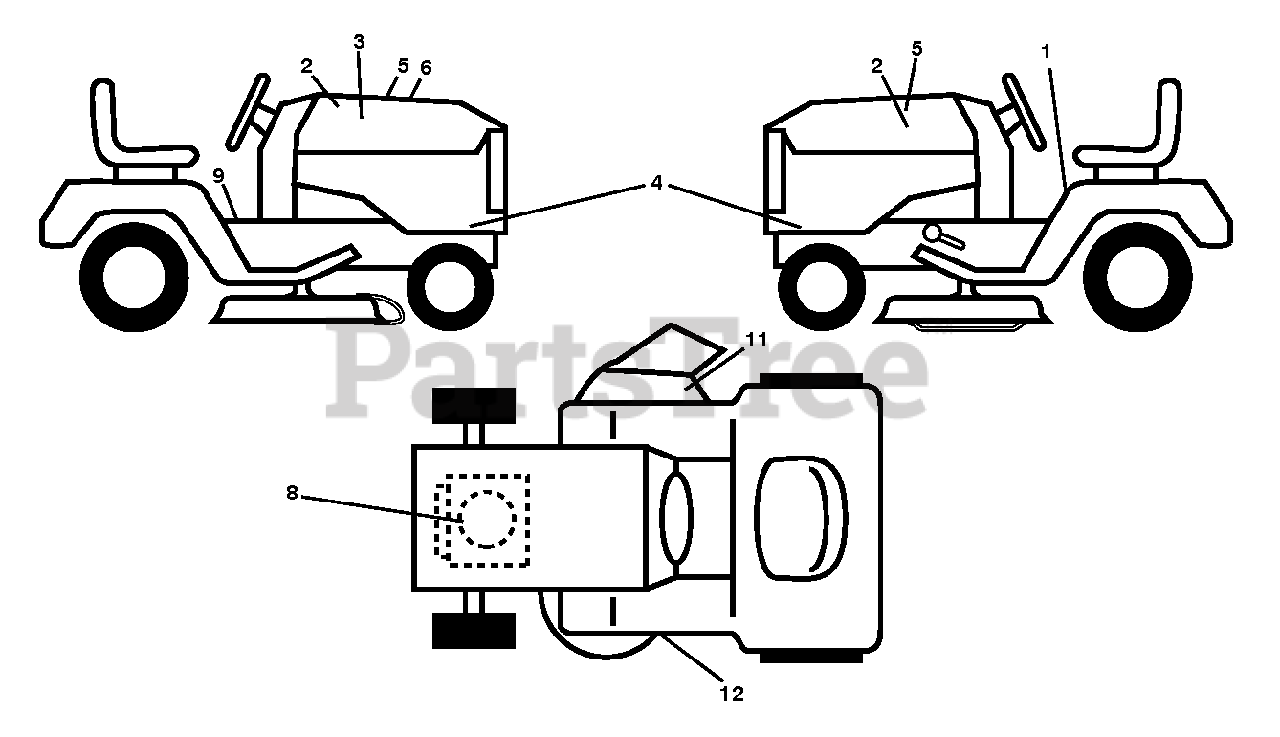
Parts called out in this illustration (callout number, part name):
1	DECAL.FENDER.WARNING
2	RP.DECAL.BADGE.170MM.TEXTLOGO
4	DECAL.SIDE.PANEL.LTH2038
5	RP.DECAL.BADGE.170MM.TEXTLOGO
6	DECAL.WARNING.CUST.RESP.E85.
8	Decal, Engine BS 20HPXRD
9	DECAL BTRY SYMBOLS
11	DECAL.WARN.KEEP.HAND.AWAY
12	DECAL.V-BELT.SCHEMATIC.36/38/9
